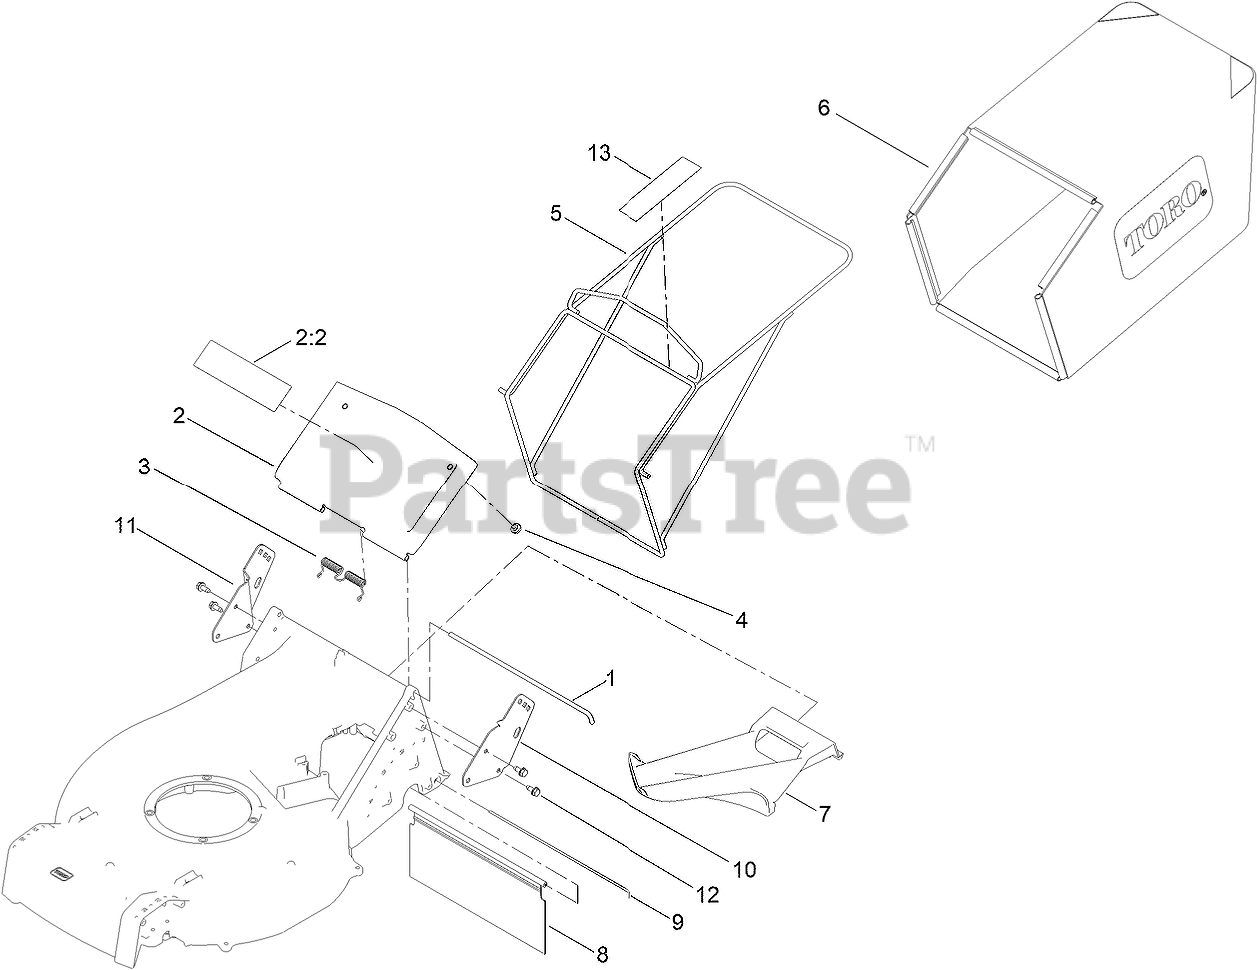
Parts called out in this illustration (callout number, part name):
1	ROD-DOOR, BAG
2	BAG DOOR ASM
2:2	DECAL-WARNING
3	SPRING-TORSION
4	BUMPER
5	FRAME-BAG
6	BAG-GRASS
7	PLUG-MULCH
8	SHIELD-TRAILING
9	ROD-SHIELD, TRAILING
10	BRACKET-MOUNT, HANDLE (LH)
11	BRACKET-MOUNT, HANDLE (RH)
12	SCREW-HWHTF
13	Decal-Warning
